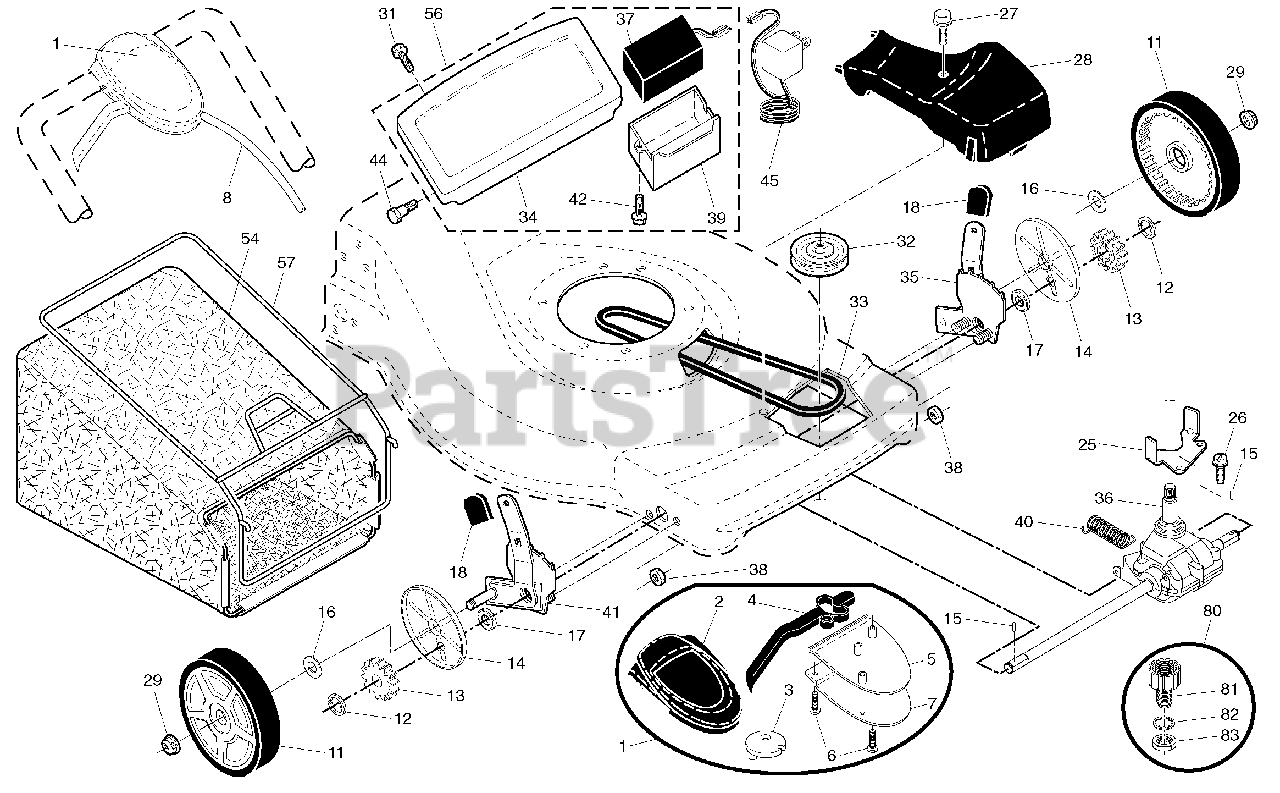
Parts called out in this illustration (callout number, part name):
1	Drive Control Assembly
2	Cover, Drive Control, Top
3	Pulley
4	Lever, Drive Control
5	Cover, Drive Control, Bottom
6	Screw, Torx Head #8 x 5/8
7	Mounting Bracket, Drive Control
8	Cable, Drive Control
11	Wheel & Tire Assembly
12	E-Ring
13	Gear, Pinion
14	Dust Cover
15	Pawl, Drive
16	Washer, Flat 3/8
17	Bearing, Wheel Adjuster
18	Selector Knob
25	Belt Keeper
26	Screw, Hi-Lo Thread
27	Pan Head Tapping Screw #10-24 x 2-3/4
28	Drive Cover
29	Locknut, Hex
31	Screw, Trimplate
32	Drive Pulley
33	V-Belt
34	Trimplate
35	Kit, Wheel Adjuster, LH
36	Gearcase Assembly, Complete
37	Battery
38	Locknut, Hex 1/4-20
39	Battery Box
40	Spring
41	Kit, Wheel Adjuster, RH
42	Screw, Battery Box
44	Screw, Trimplate
45	Charger, Battery
54	Grassbag Assembly
56	Trimplate, Battery Box and Battery Assembly
57	Frame, Grassbag
80	Kit, Water Washout
81	Fitting, Hose, Water Washout
82	Washer, Lock, Internal Tooth
83	Locknut, Hex, with O-Ring
